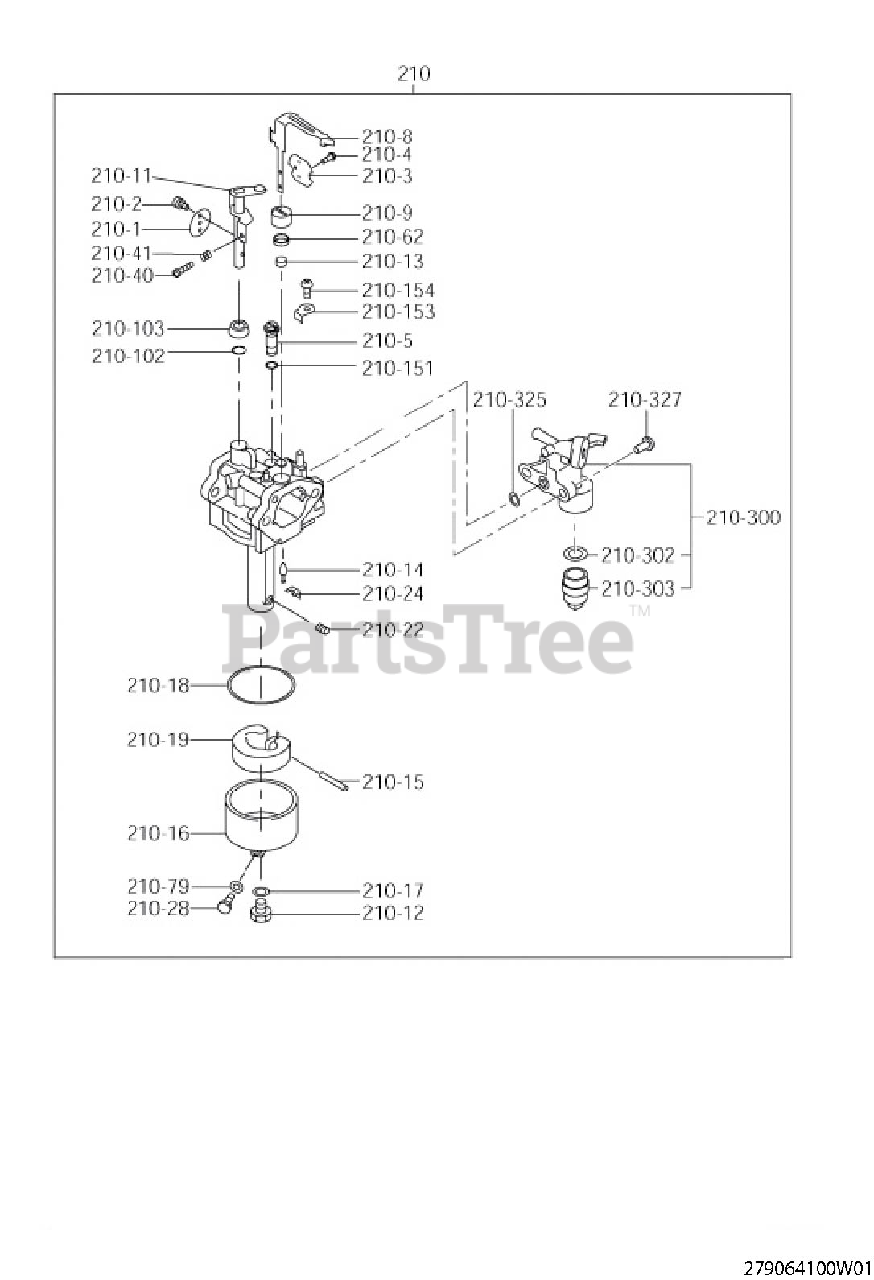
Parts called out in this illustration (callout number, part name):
210-0	CARBURETOR AY
210-1	THROTTLE VALVE
210-2	SCREW
210-3	CHOKE VALVE
210-5	PILOT JET
210-8	CHOKE LEVER
210-11	THROTTLE SHAFT-A
210-12	BOLT
210-14	NEEDLE VALVE
210-15	PIN
210-16	FLOAT BODY-A
210-17	INSERT WASHER
210-18	PACKING
210-19	FLOT-A
210-22	MAIN JET
210-24	CLIP
210-28	BOLT
210-40	SCREW
210-41	SPRING
210-79	WASHER
210-102	SEAL
210-103	RING
210-151	O-RING
210-153	PLATE
210-154	SCREW
210-300	COCK BODY-A
210-302	PACKING
210-303	CUP
210-325	O-RING
210-327	SCREW
